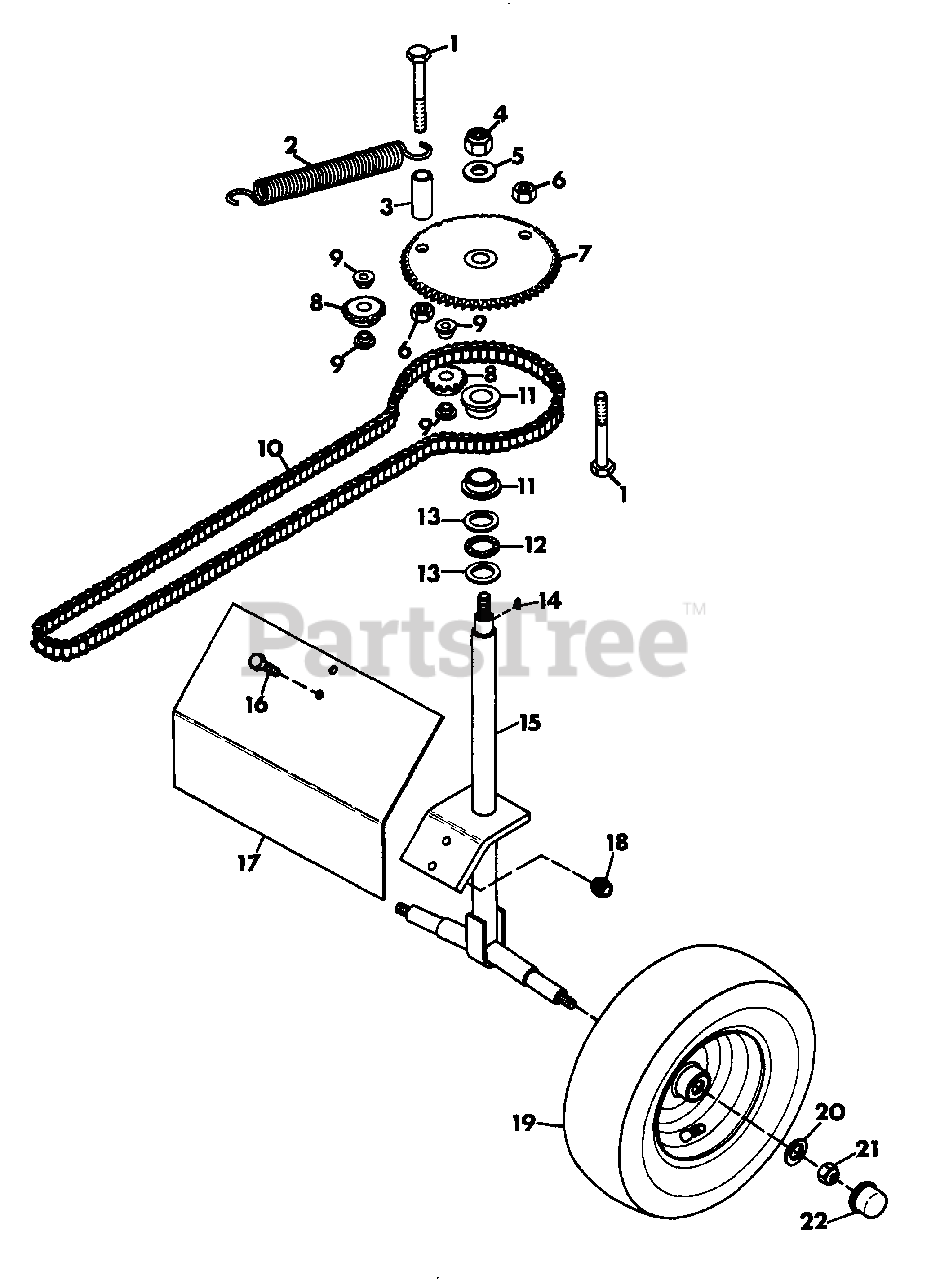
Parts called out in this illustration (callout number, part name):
1	BOLT, HEX 1/2-13X3.25
2	SPRING
3	SPACER, .850X.546X2.18
4	NUT, LOCK 7/8-9
5	WASHER, FLAT .969X2.250X.165
6	NUT, HEX 1/2-13
7	SPROCKET, 60-T #40
8	SPROCKET, DRIVE
9	BUSHING
10	CHAIN, #40
11	BEARING, FLANGED
12	BEARING, NEEDLE THRUST
13	BEARING, THRUST RACE
14	KEY, WOODRUFF .250X.875 HARD #A
15	WELDMENT, PRO MASTER AXLE
16	BOLT, HEX 1/2-13X1.25
17	FENDER, PRO MASTER
18	NUT, LOCK 1/2-13
19	WHEEL, PRO MASTER REAR
20	WASHER, FLAT .812X1.496X.134
21	NUT, LOCK 3/4-10
22	CAP
